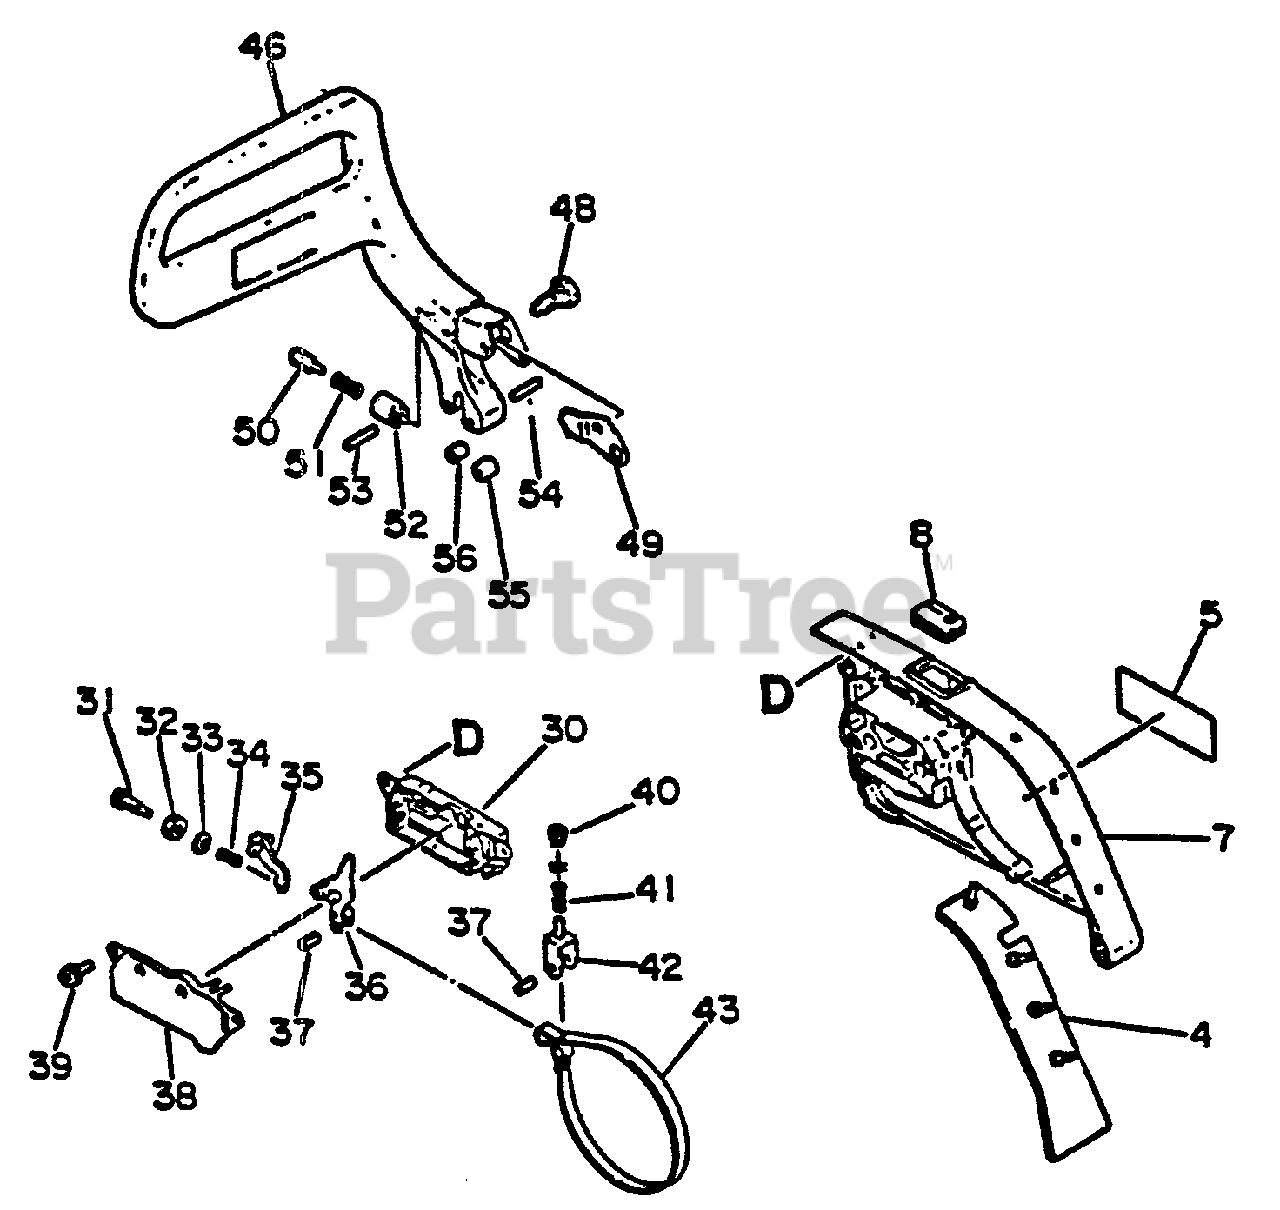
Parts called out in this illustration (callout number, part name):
5	LABEL - ECHO
7	GUARD, SPROCKET
8	CHAIN BRAKE ASSY
30	COVER, BRAKE
34	SPRING, BRAKE
35	STOPPER, BRAKE
36	LEVER, BRAKE
37	PIN - SPRING -- 4X10
38	COVER, BRAKE
39	SCREW - 4X10
42	ADJUSTER, BRAKE BAND
43	BAND, BRAKE
46	BRAKE LEVER ASSY
56	SPACER
